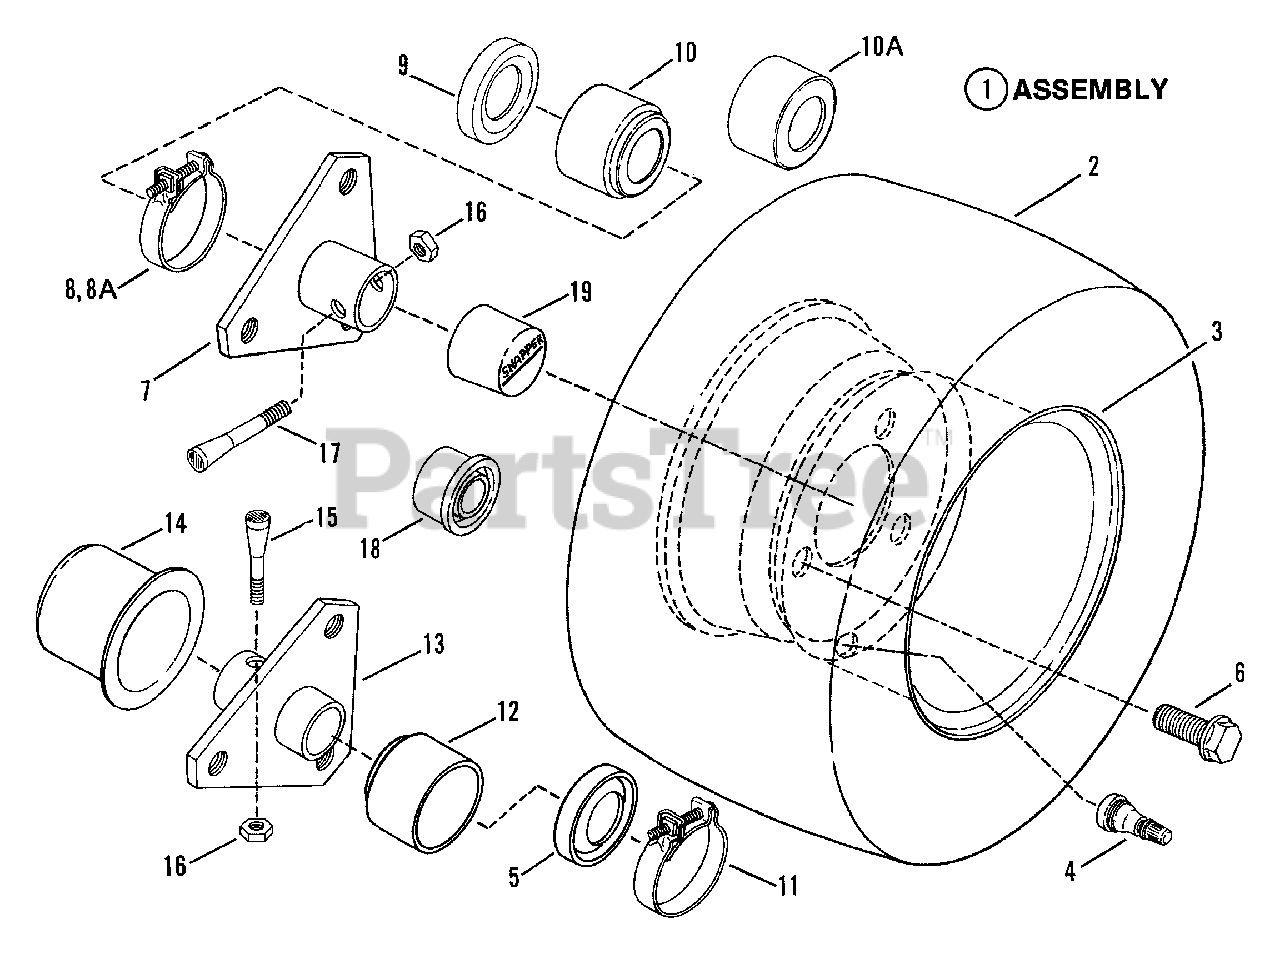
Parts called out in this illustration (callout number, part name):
1	ASSEMBLY, Rear Tire & Rim (25 & 26" Models)
2	TIRE, Wide, 16/6.50x8(28,30, & 33" Models)
3	RIM, Wide (For 16/6.50x8 Tire)(28,30 & 33" Models)
4	VALVE, Air (Snap-in)
5	SEAL, Oil Left Hand
6	BOLT, 1/2-20x3/4" Lug
7	HUB, Rear Wheel, Right Hand
8	CLAMP, Right Hand (12 & 14 HP Models)
8A	CLAMP, Right Hand (6.5 & 8 HP Models)
9	SEAL, Oil, Right Hand
10	BOOT, Right Hand(12 & 14 HP Models)
10A	BOOT, Right Hand (6.5 & 8 HP Models)
11	CLAMP, Left Hand(12 & 14 HP Models)
12	BOOT, Left Hand(12 & 14 HP Models)
13	HUB, Rear Wheel, Left Hand
14	HUB-CAP, Left Hand
15	BOLT, 5/16-24x1-518" Tapered, Left Hand
16	NUT, 5/16-24 Lock
17	BOLT, 5/16-24x2" Tapered, Right Hand
18	CAP, Dust, Left Hand (6.5 & 8 HP Models)
19	HUB, CAP, Right Hand
